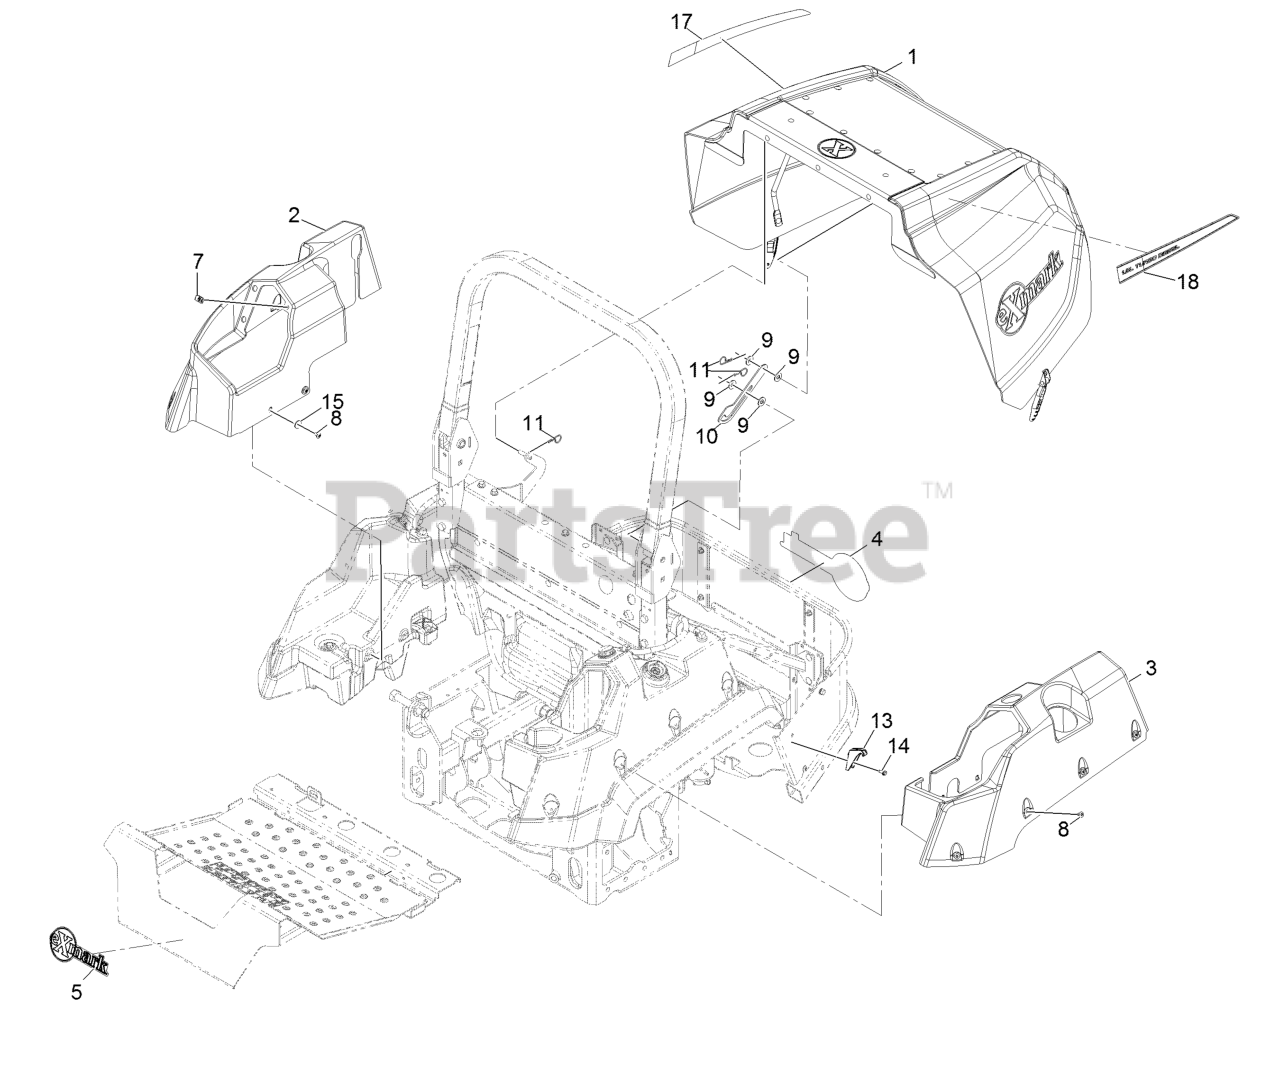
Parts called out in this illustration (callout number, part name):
1	Hood ASM
2	Cover-Tank, RH
3	Cover-Tank, LH
4	Decal-Exmark
5	Decal-Exmark
8	Screw-Torx
9	Washer-Flat
10	Prop-Hood
11	Pin-Cotter, Hair
13	Latch-Catch
14	Screw-HWH
15	Washer-Flat
17	Decal-Turbo Diesel-RH
18	Decal-Turbo Diesel-LH
